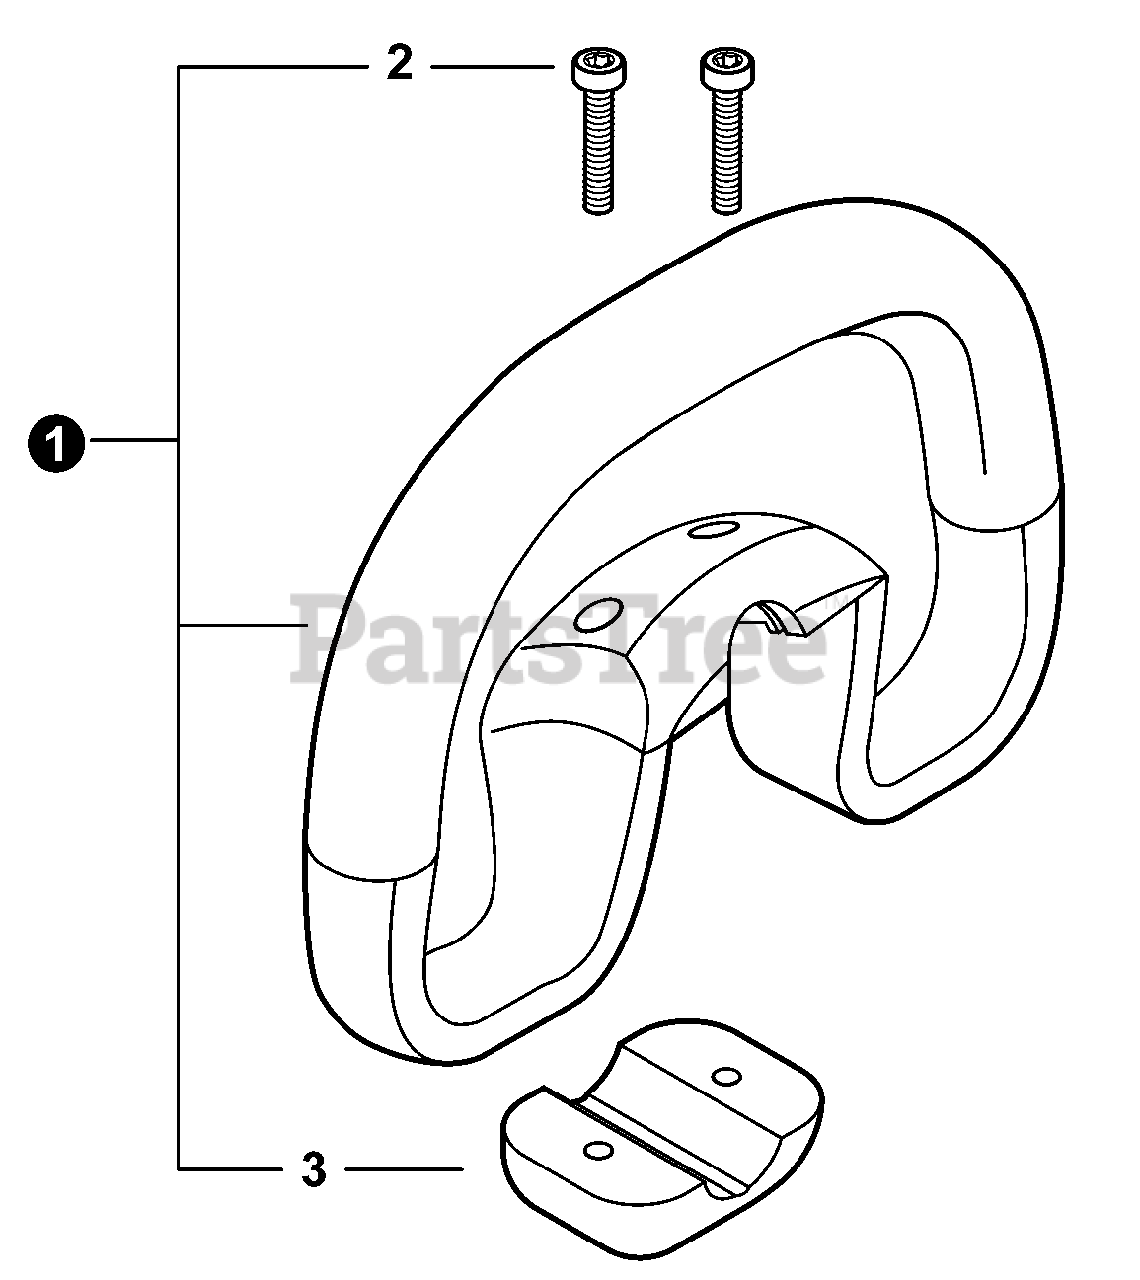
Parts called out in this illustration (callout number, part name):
1	HANDLE ASSY - SUPPORT
2	BOLT, TORX 5×35
3	BRACKET, HANDLE
